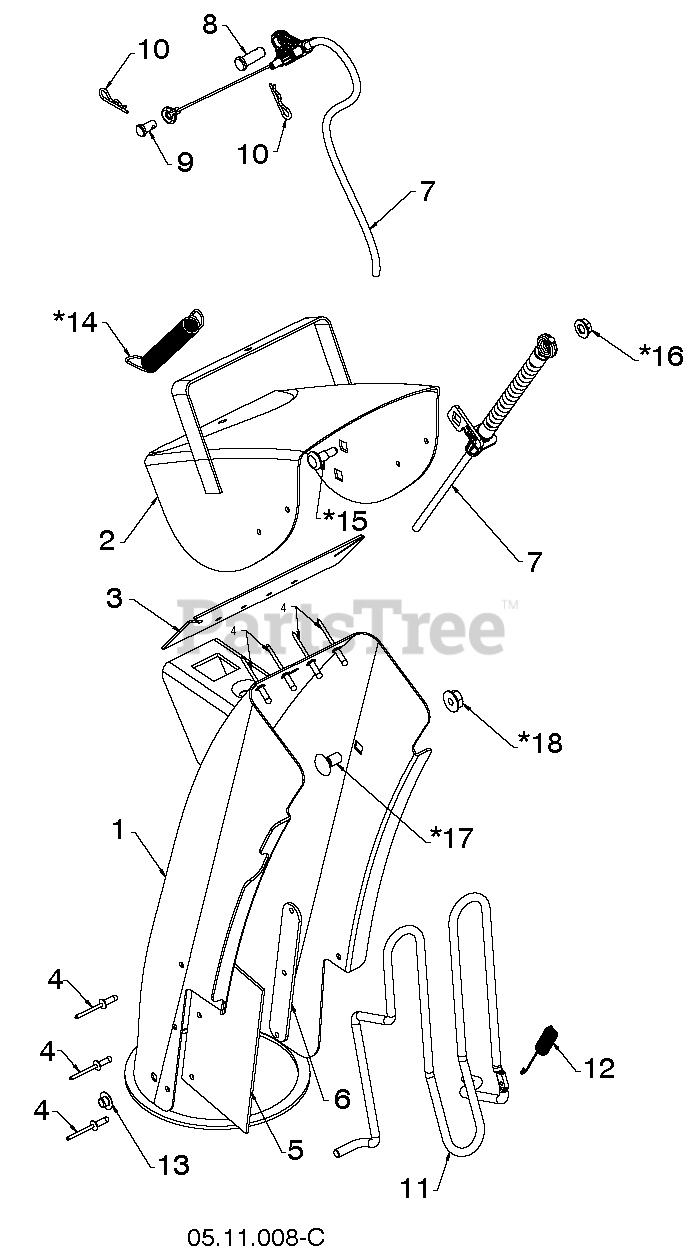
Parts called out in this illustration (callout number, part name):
1	CHUTE.WELDMENT.PNT.ORANGE
2	DEFLECTOR.WELDMENT.PNT.ORANGE
3	SEAL.DEFLECTOR
4	RIVET BLIND
5	SHIELD.SNOW.CHUTE
6	STRAP.SHEILD.RETAINER
7	Deflector Chute Control Cable
8	Clevis Pin, 5/16 X .875
9	Clevis Pin, .25 X .31
10	Hair Pin, .059 X 1.125
14	SPRING
15	Shoulder Bolt, 1/4
16	Flange Hex Lock Nut, 1/4-20 Large
17	Carriage Bolt, 5/16-18 X 5/8 Black
18	LOCKNUT-FLANGE 5/16-18
